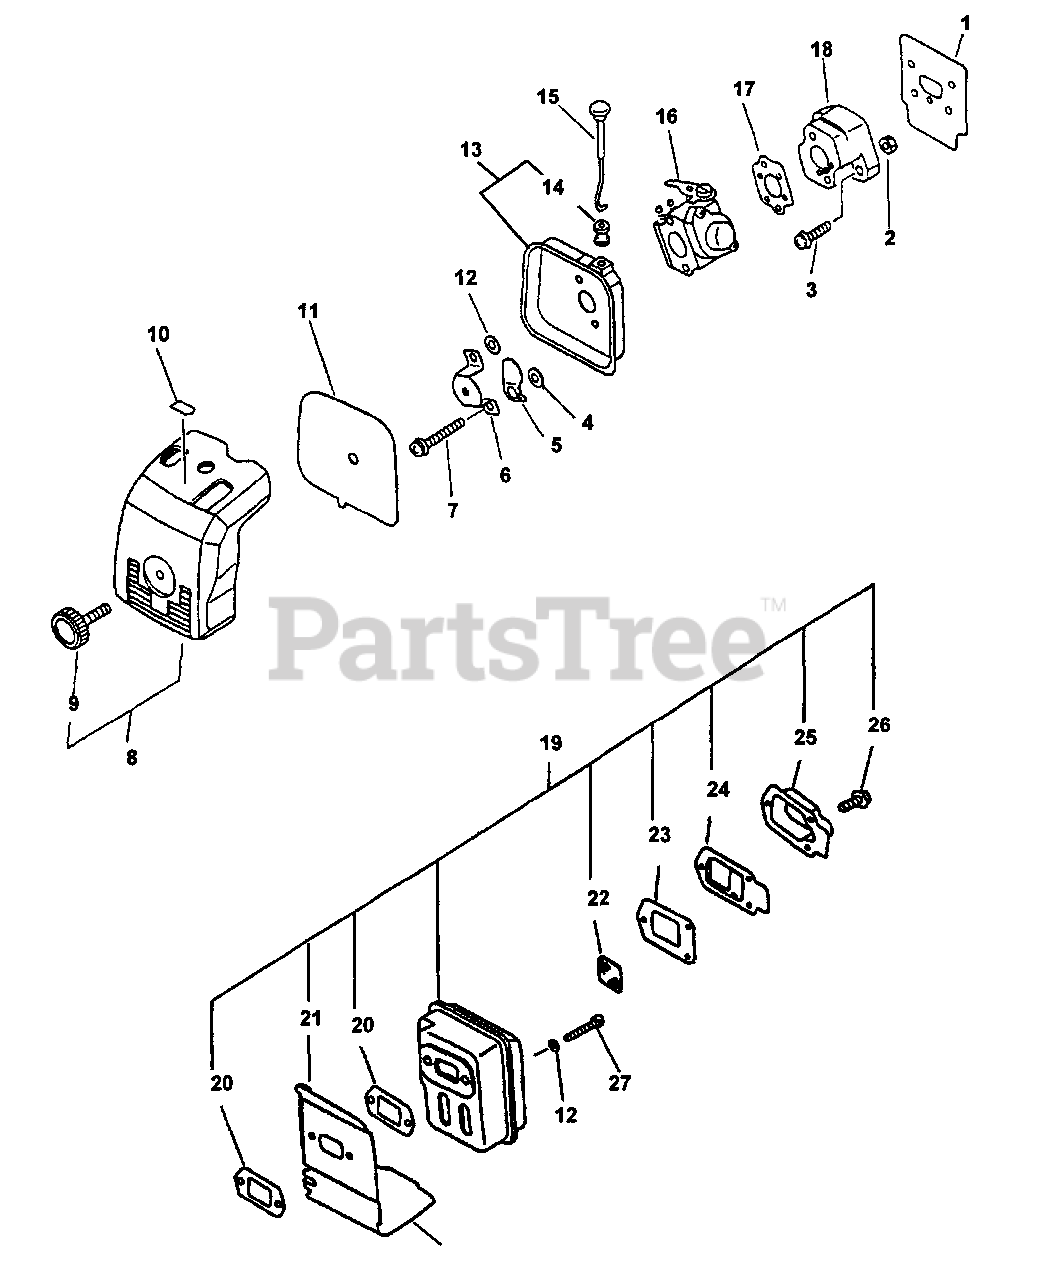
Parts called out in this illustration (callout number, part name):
1	SHIELD, INTAKE
3	SCREW - 5X20
4	WASHER - 5
5	SHUTTER, CHOKE
6	PLATE, PREVENT
7	SCREW - 5X57
8	AIR FILTER COVER ASSY
9	THUMBSCREW
10	LABEL - CHOKE
11	FILTER, AIR - HEAVY DUTY
12	WASHER - 5
13	CASE, AIR FILTER
15	ROD, CHOKE
16	CARBURETOR WT-424A
17	GASKET, INTAKE
18	INSULATOR, INTAKE
19	MUFFLER ASSY
20	GASKET, EXHAUST
21	COVER, EXHAUST
22	SCREEN, SPARK ARRESTOR
23	GASKET, EXHAUST
24	GASKET, EXHAUST - INNER
25	GUIDE, EXHAUST - OUTER
26	SCREW - 4X10
27	SCREW - 5X55
